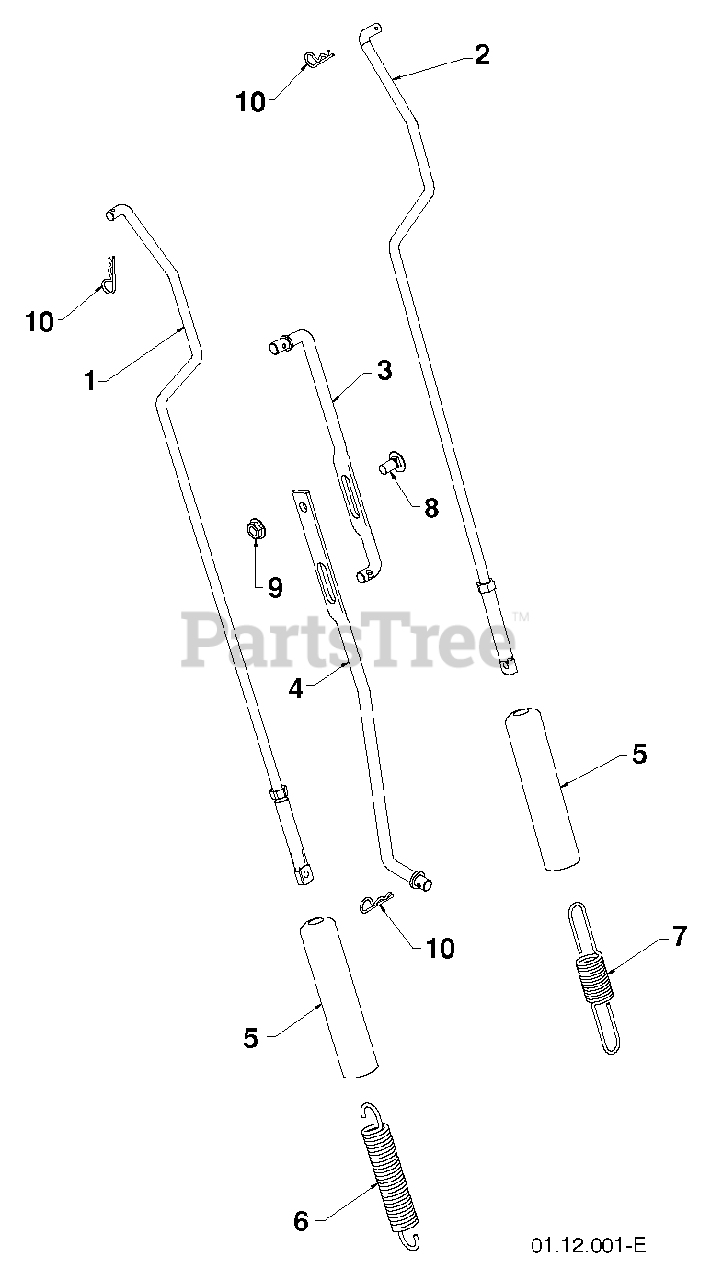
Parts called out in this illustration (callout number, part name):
1	ROD.IMPELLER
2	ROD.TRACTION
3	ROD, UPPER SPEED CONTROL
4	ROD, LOWER SPEED CONTROL
5	SLEEVE, SPRING
6	SPRING.CONTROL.ROD.SNOW
7	SPRING.TRACTION.ROD.SNOW
9	NUT.FLANGE.5/16
10	SPRING RETAINER
